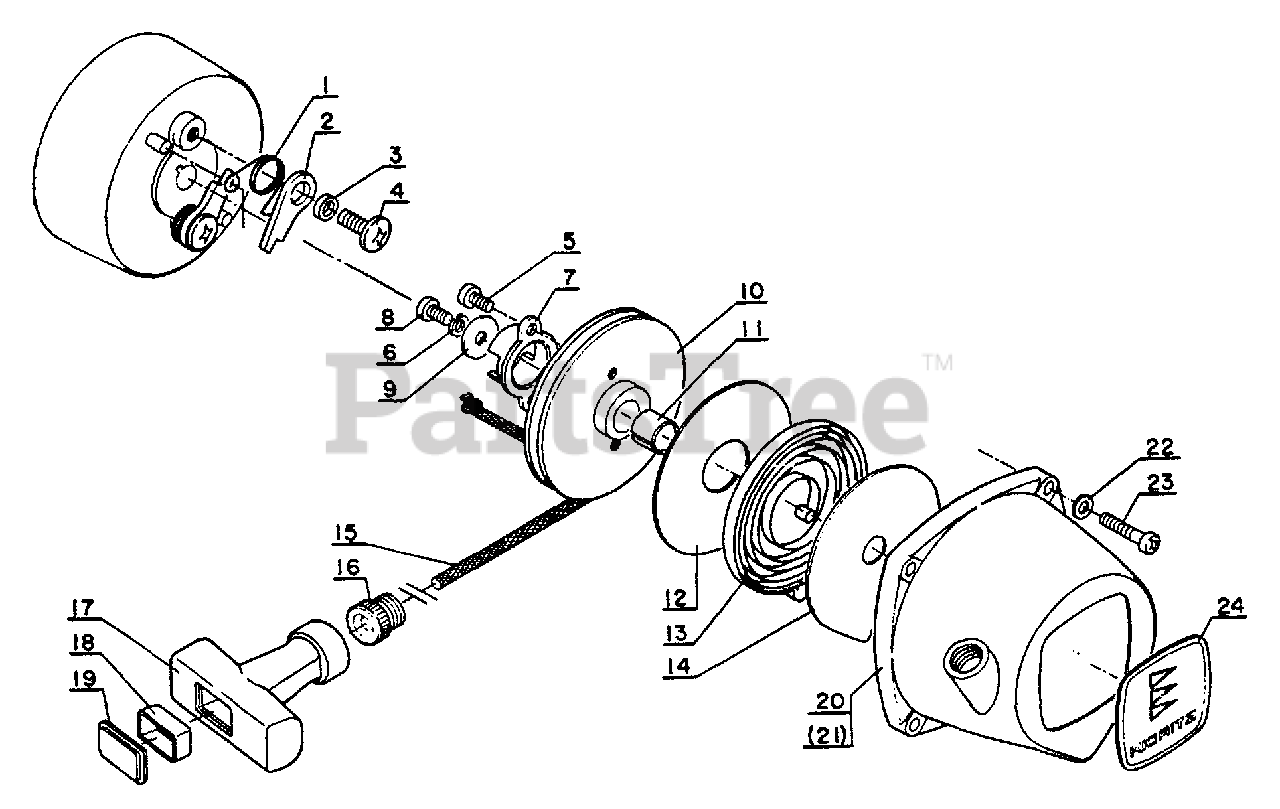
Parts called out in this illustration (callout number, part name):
1	SPRING, RETURN
2	PAWL, STARTER
3	SPACER 5.2×8×2.1
4	SCREW
5	SCREW 4×8
6	WASHER, SPRING 4 MM
7	PAWL CATCHER
8	SCREW 4×6
9	WASHER 4.1×15.5×1T
10	REEL, ROPE
12	PLATE, STARTER
13	SPRING, RECOIL
14	PLATE, STARTER
15	ROPE, STARTER 3.5×850
16	GUIDE, ROPE
17	GRIP, STARTER
19	COVER, HANDLE
20	CASE, STARTER
22	WASHER 4 MM
23	SCREW 4×20
24	PLATE, NAME
